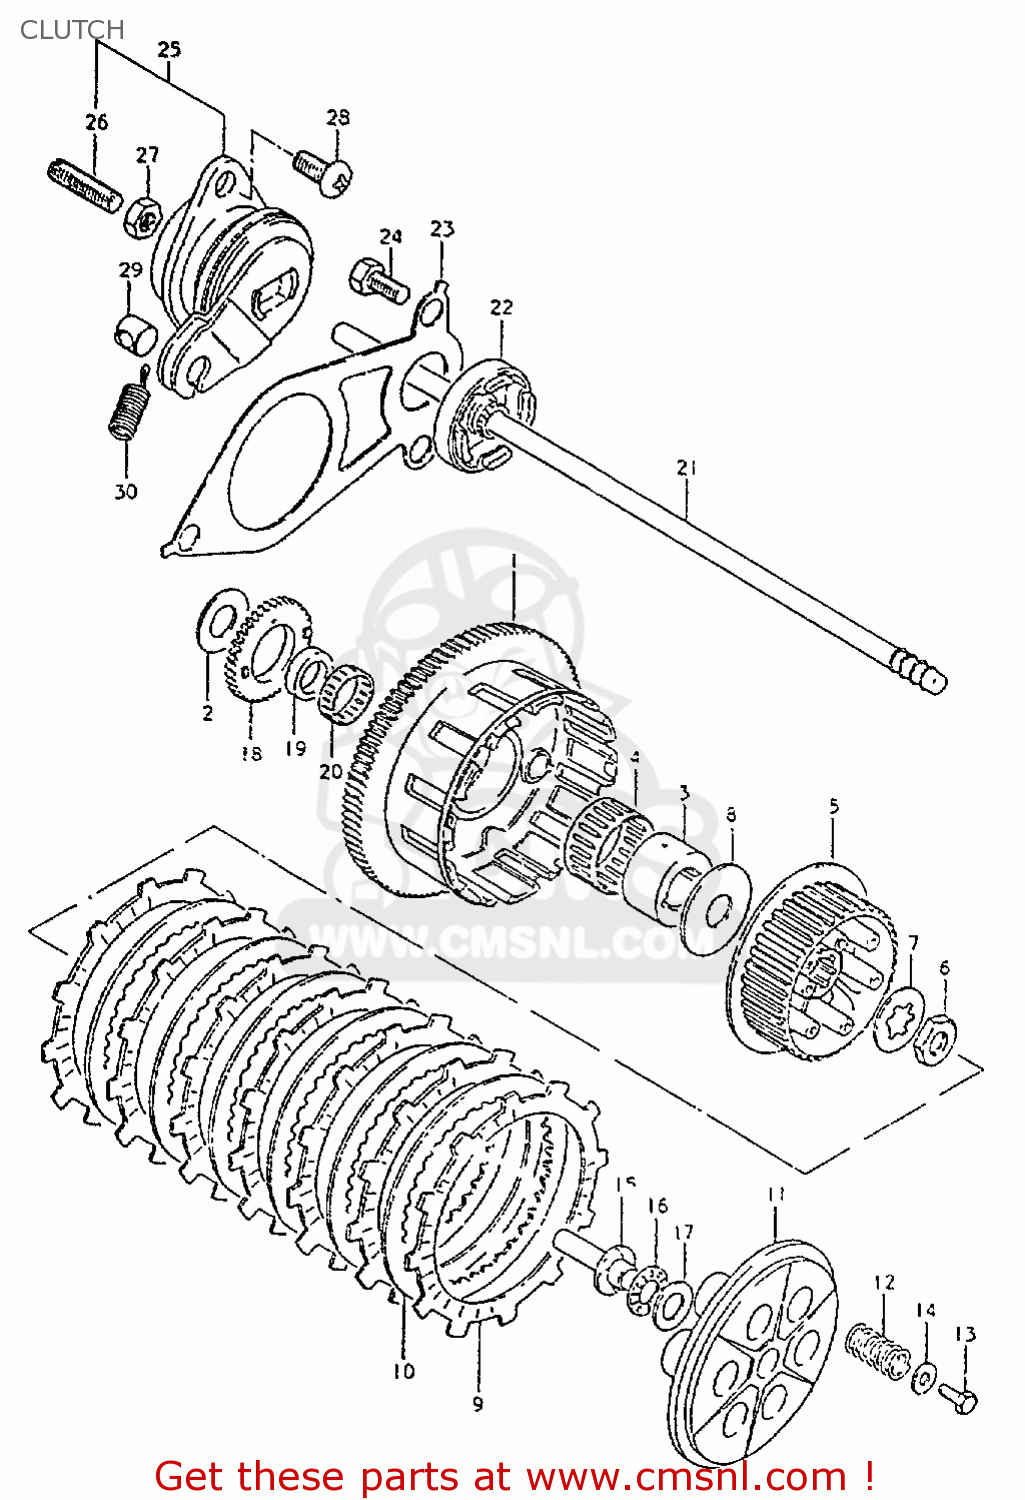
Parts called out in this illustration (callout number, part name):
1	GEAR ASSEMBLY,PRIMARY DRIVE NT:87
2	WASHER
3	SPACER,PRIMARY DRIVEN
4	BEARING
5	HUB,CLUTCH SLEEVE
6	NUT
7	WASHER,LOCK
8	WASHER(25X66X3.5)
9	PLATE,CLUTCH DRIVE (NAS)
10	PLATE,CLUTCH DRIVEN (NAS)
11	DISC,CLUTCH PRESSURE
12	SPRING
13	BOLT, UPPER
14	WASHER
15	PIECE,CLUTCH PUSH
16	BEARING(15X28X2)
17	WASHER
18	GEAR,ENG OIL PUMP DRIVE(NT:38)
19	SPACER,OIL PUMP DRIVE GEAR
20	BEARING(36X40X10)
21	ROD,CLUTCH PUSH
22	OIL SEAL
23	PLATE,CLUTCH PUSH ROD
24	BOLT
25	SCREW ASSEMBLY,CLUTCH RELEASE
26	SCREW
27	NUT 6MM
28	SCREW 6X12
29	PIECE,RELEASE ARM END
30	SPRING
